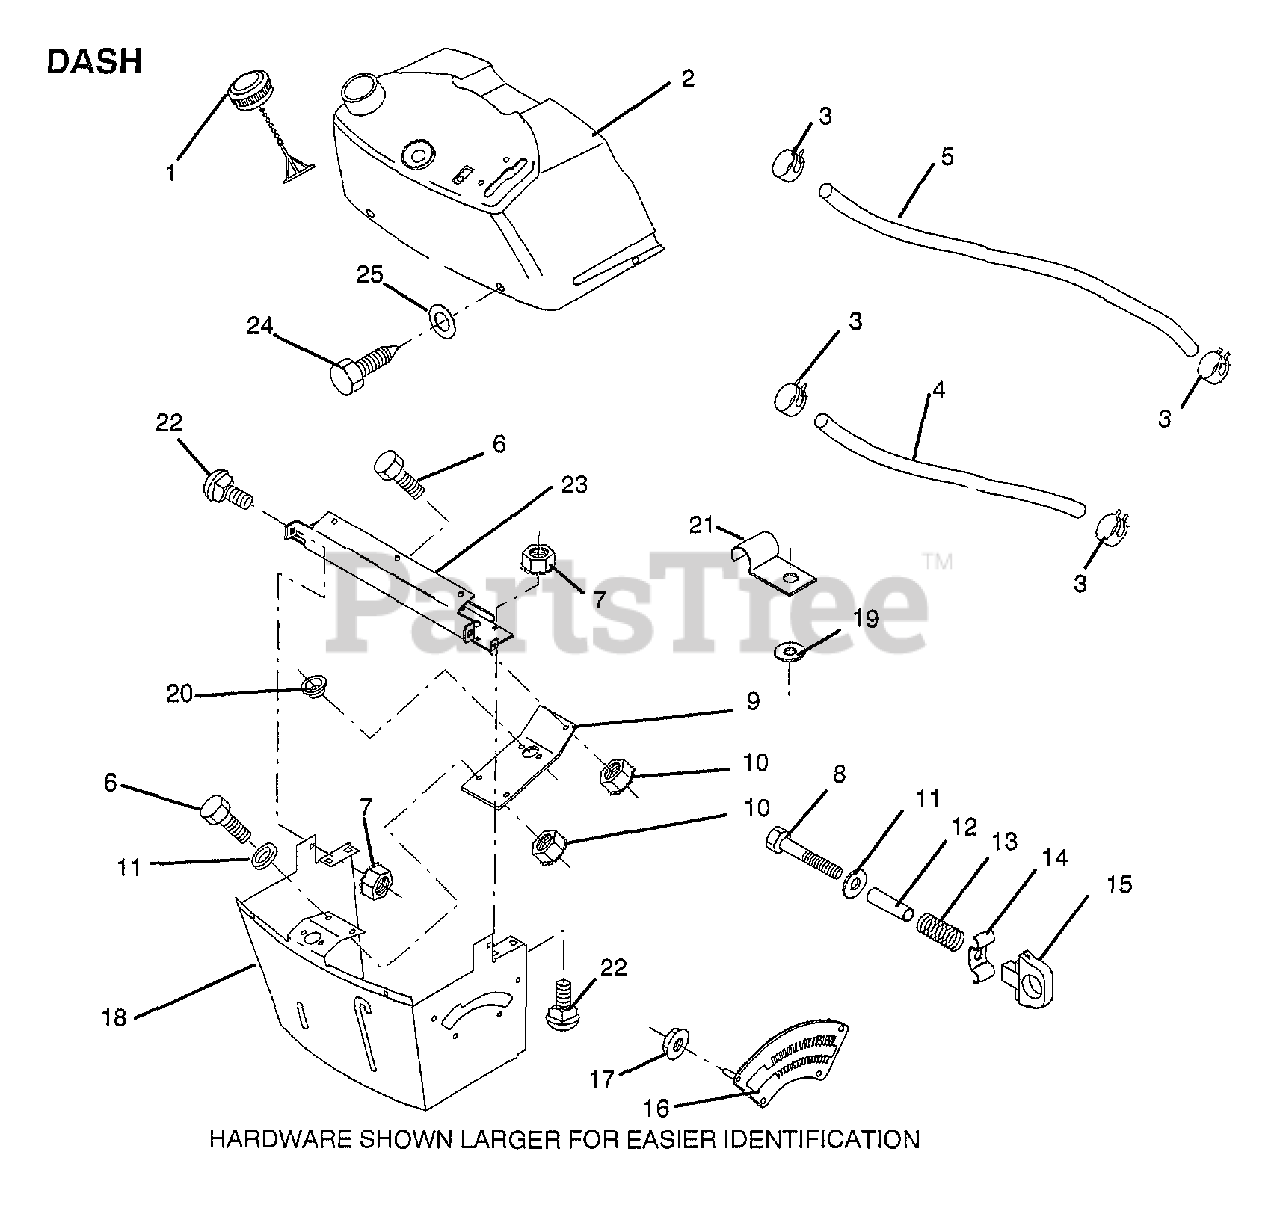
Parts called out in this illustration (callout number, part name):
3	HOSE CLAMP
4	FUEL LINE T
7	NUT
8	BOLT
10	LOCKNUT
11	WASHER
12	SPACER SPLIT
13	SPRING T
14	HEIGHT ADJ
15	KNOB
16	ADJUSTER QUAD
17	NUT
18	SUPPORT DASH
19	WASHER PM
21	CLIP T
22	BOLT
